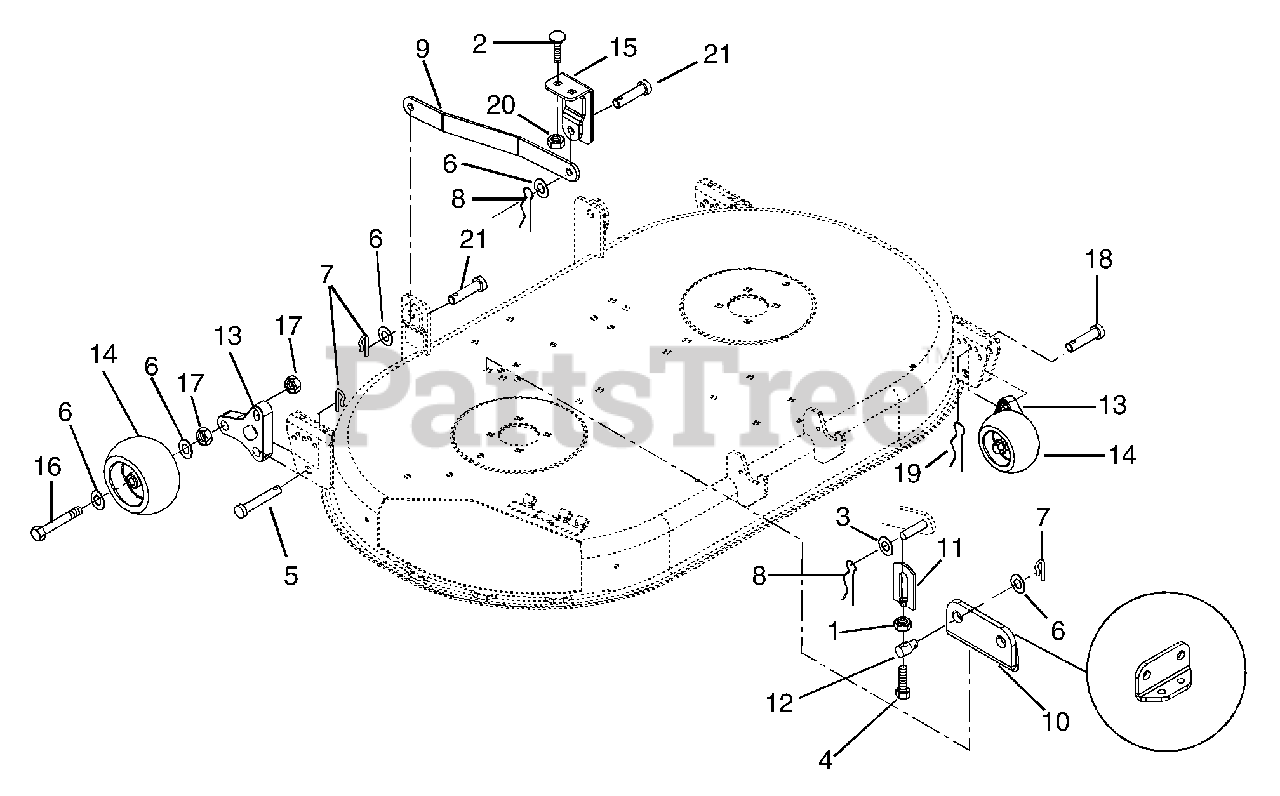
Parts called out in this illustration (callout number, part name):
1	@NUT-LK-CTR .38-16 YWZC
2	@BLT-RDHDSQNK .38-16X.75 G5YZ
3	WSHR-FL-STL .630X1.005X.062 YZ
4	BLT-HEX .38-16X2.50 FTH YWZC
5	PIN-CLEV .50X1.38 YWZC
6	WSHR-FL-STL .505X.880X.072 YWZ
7	CLIP, SPRING
8	PIN-HAIR-EXT .12X.31X2.37 YWZC
9	LINK, LIFT (SIERRA)
10	BRACKET, LIFT
11	WELDMENT, ADJUSTMENT LINK
12	TRUNNION
13	BRACKET, ROLLER ADJUST.
14	WHEEL 5 X 3
15	WELDMENT, DECK STOP BRACKET
16	@BLT-HEX .50-13X4.00 GR5 YWZC
17	NUT-LK-CTR-JAM .50-13 YWZC(ND)
18	PIN-CLEV .31X1.38 YWZC
19	PIN-HAIR INT .08X.38X1.42 YWZC
20	@NUT-LK-NYL .38-16 YWZC
21	PIN-CLEV .50X1.00 YWZC
